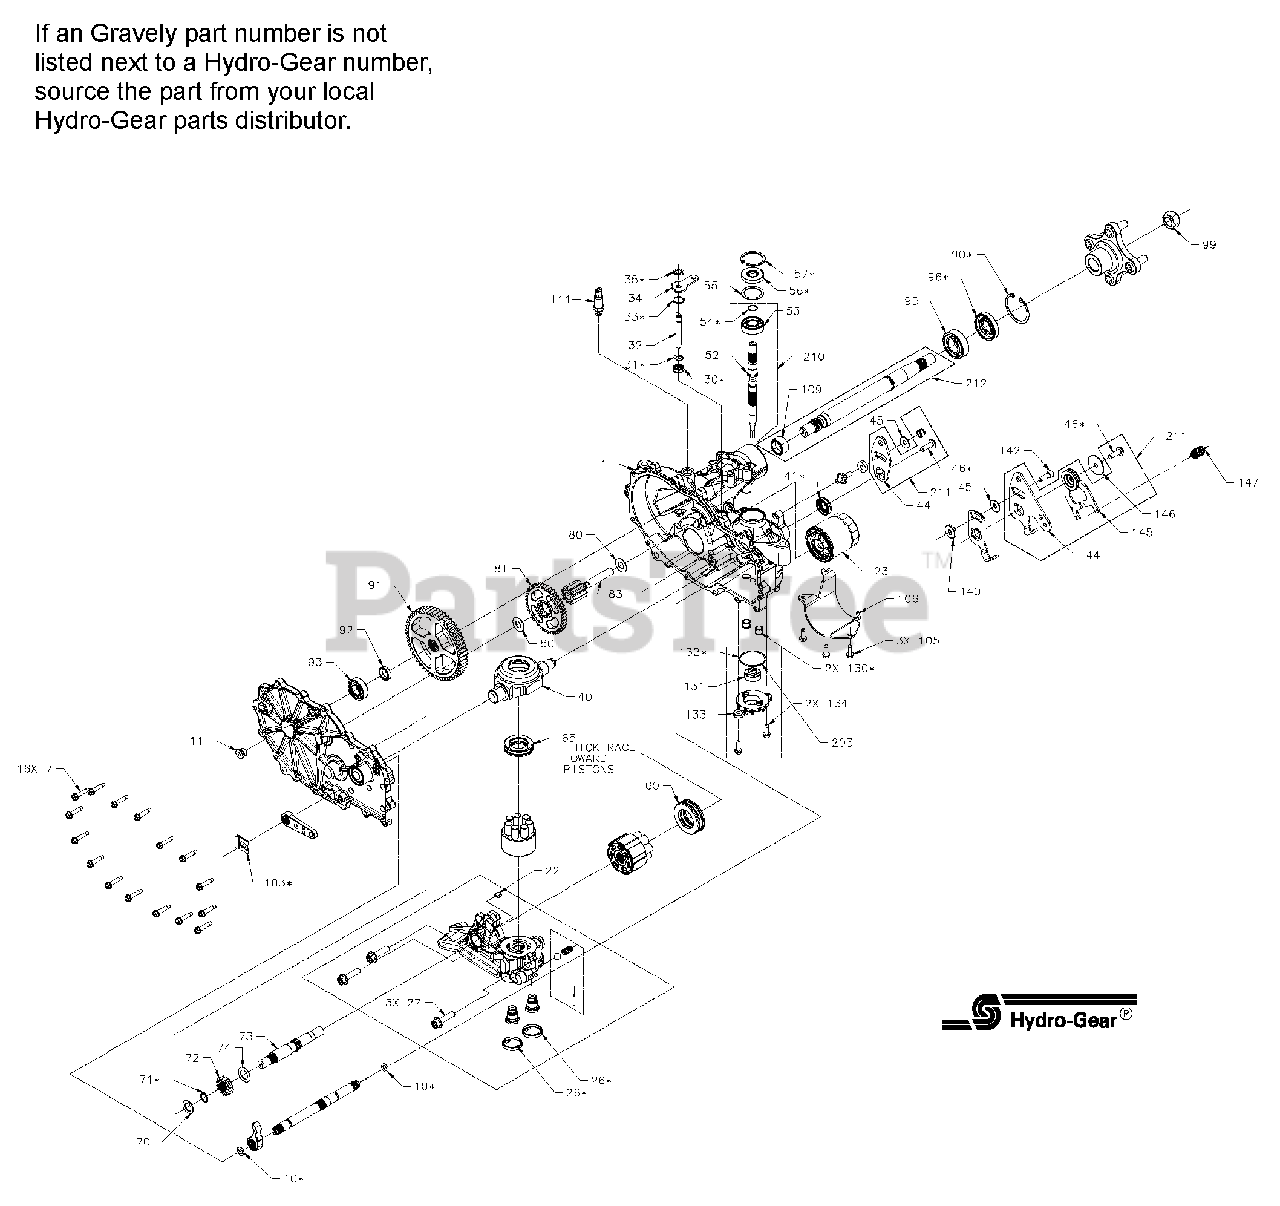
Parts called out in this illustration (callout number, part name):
1	KIT, HOUSING, MAIN, RH, CHRG, CNTL
2	KIT, COVER, SIDE, RH
7	SCREW,HEX WASHER 1/4-20X1.125
13	SEALANT TUBE 10.1OZ.
22	PLATE, BYPASS
23	OIL FILTER, TRANSMISSION
26	SEAL, PLUG 1.375 X .250
30	SEAL, LIP .375X.75X.25
31	RING. RETAINING
32	ROD, BYPASS
33	RING, RET .750
34	ARM, BYPASS
35	RING, RTNG .
40	TRUNNION, SWASHPLATE
41	SEAL, LIP 18X32X7
45	WASHER
46	TWHCS 5/16-24 X 1.00
55	WASHER 1.23X1.56X.04
56	SEAL, LIP 17X40X7
57	RING, RET 1.56 INT
60	HG THRUST BEARING (51462)
64	HG 16CC CYLINDER BLOCK (71579)
65	BEARING. THRUST 30 X 52 X 13
69	ASSY, BLOCK 7 PISTON
70	WASHER .63X1.0X.05
71	RING, RET 62 EXT
72	GEAR, 13T, STEEL
73	SHAFT, MOTOR
74	WASHER .71 X 1.16 X .04
80	WASHER .5X1.0X.032
82	GEAR, 11T, STEEL
83	JACK SHAFT (PIN)
90	RING, RETAINING
95	BEARING, BALL 25.4 X 52 X 15
96	SEAL, LIP
97	HUB, HYDROGEAR P/N 71691
99	NUT, HEX, LOCK 3/4-16
100	PAWL, BRAKE
101	KIT, BRAKE SHAFT
102	BRAKE ARM HG 71957
103	RING, RETAINING
105	HFHCS 1/4-20X.75
106	GUARD, FILTER, RH
111	KIT, FITTING 1/2 BEADED 9/16
120	FAN, 7.0 W/ INSERT
121	DISC, PULLEY, CUPPED, 4.5 INCH
122	NUT, HEX 1/2-20 PATCH
124	HUB, PULLEY
130	TUBE, CONNECTING
131	GEROTOR
132	O-RING HYDROGEAR 52250
133	COVER, CHARGE PUMP
134	HFHCS 1/4-20X.75
140	SPACER
141	ARM, NEUTRAL RIGHT
142	SHCS 5/16-24X1 PATCH
147	SPRING, EXTNSN RTN - 34 LBS
156	CAP, AXLE
157	KIT, GEROTOR SEAL
159	SPRING, TORSION, CW
164	SPACER
200	KIT, SEAL
201	KIT, CENTER SECTION RH, CHRG
202	KIT, CHARGE RELIEF
203	KIT, CHARGE PUMP 71411
207	PULLEY/FAN KIT HG P/N 71694
209	HUB PULLER 4 BLT HYDGEAR 71459
210	INPUT SHAFT 2800 HYDGEAR 71442
211	RTN KIT HYDROGEAR P/N 71597
212	KIT, SHAFT, AXLE
